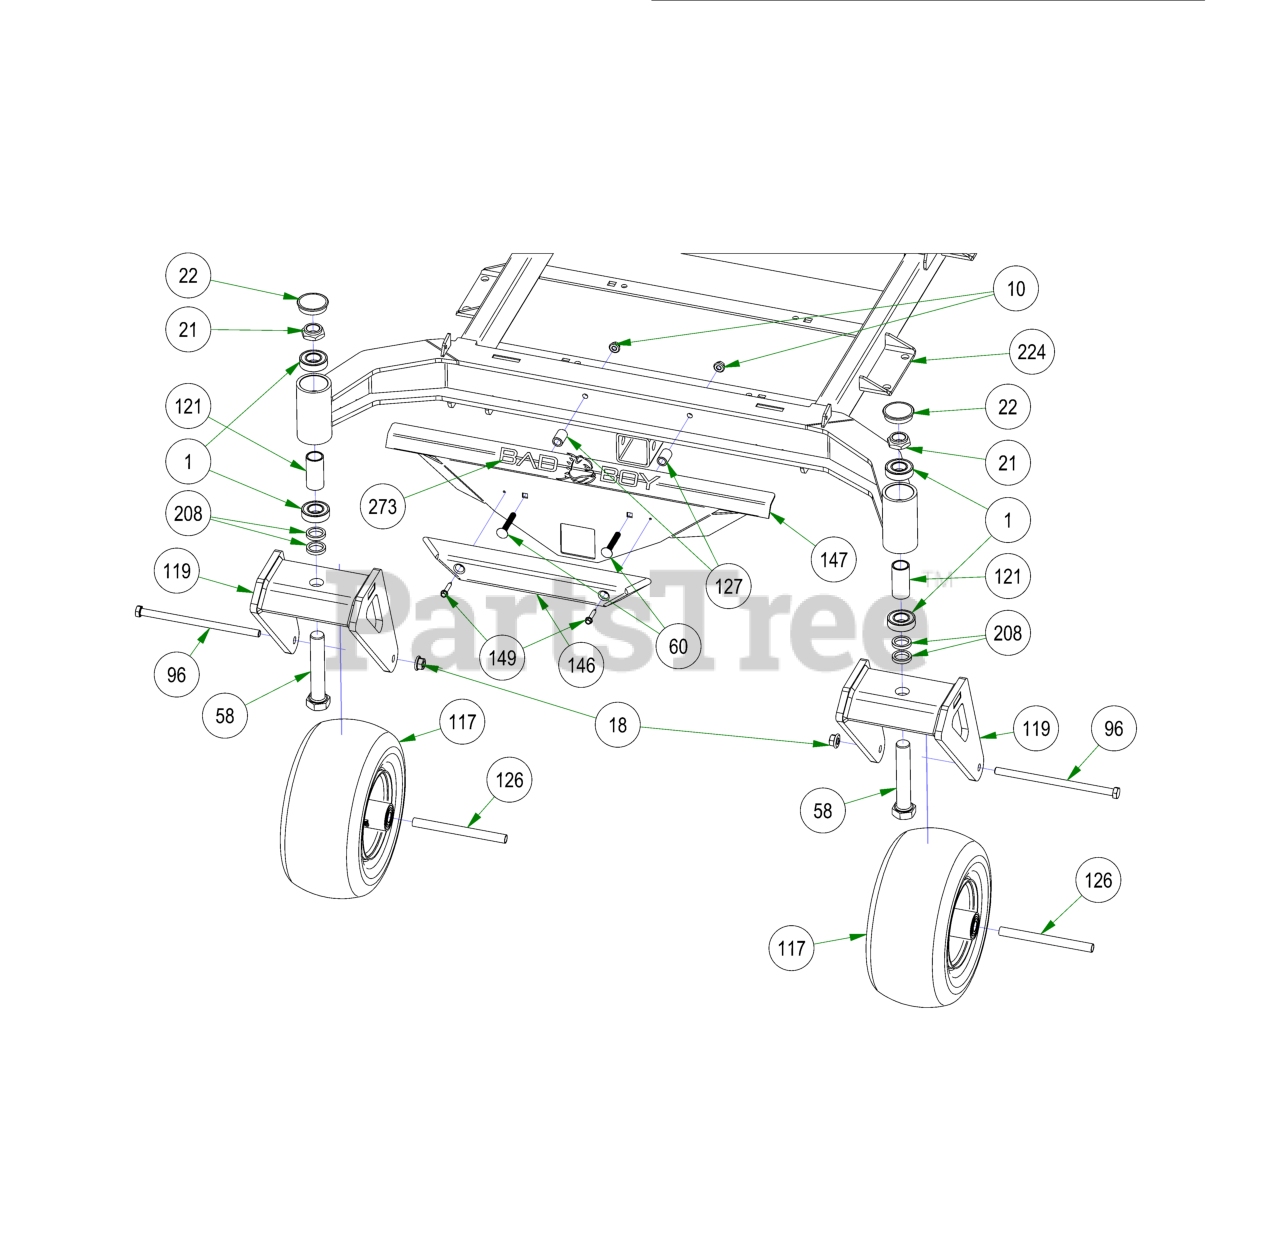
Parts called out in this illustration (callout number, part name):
1	1641 BEARING W/2 CONTACT RUBBER SEALS
10	3/8-16 NYLON INSERT FLANGE LOCKNUT (GR.F) ZINC
18	1/2-13 NYLON INSERT FLANGE LOCKNUT ZINC
21	1"-14 NYLON INSERT JAM LOCKNUT ZINC
22	2017 Bearing Cover
58	1"-14 X 5-1/2 HEX CAP SCREW (GR.8) ZINC YELLOW
60	3/8" x 2 1/2" Carriage Bolt
96	1/2-13 X 9 HEX CAP SCREW (GR.5) ZINC
117	13x6.50-6 Black No Flat Assembly
119	2019 Rebel Front Fork - Weldment - Black
121	2016 Front Bearing Spacer
126	Front Wheel Spanner
146	2017 XP Bumper
147	2019 Outlaw Rigid Front Bumper Plate-Raw
149	1/4-14 X 1-1/2 HEX WASHER UNSLOT TEK/3 ZINC
208	1.02 ID X 1.38 OD X .250 THK SPACER ZINC
224	2023 Rebel Frame - Painted
273	Flying Bulldog Front Bumper Decal
